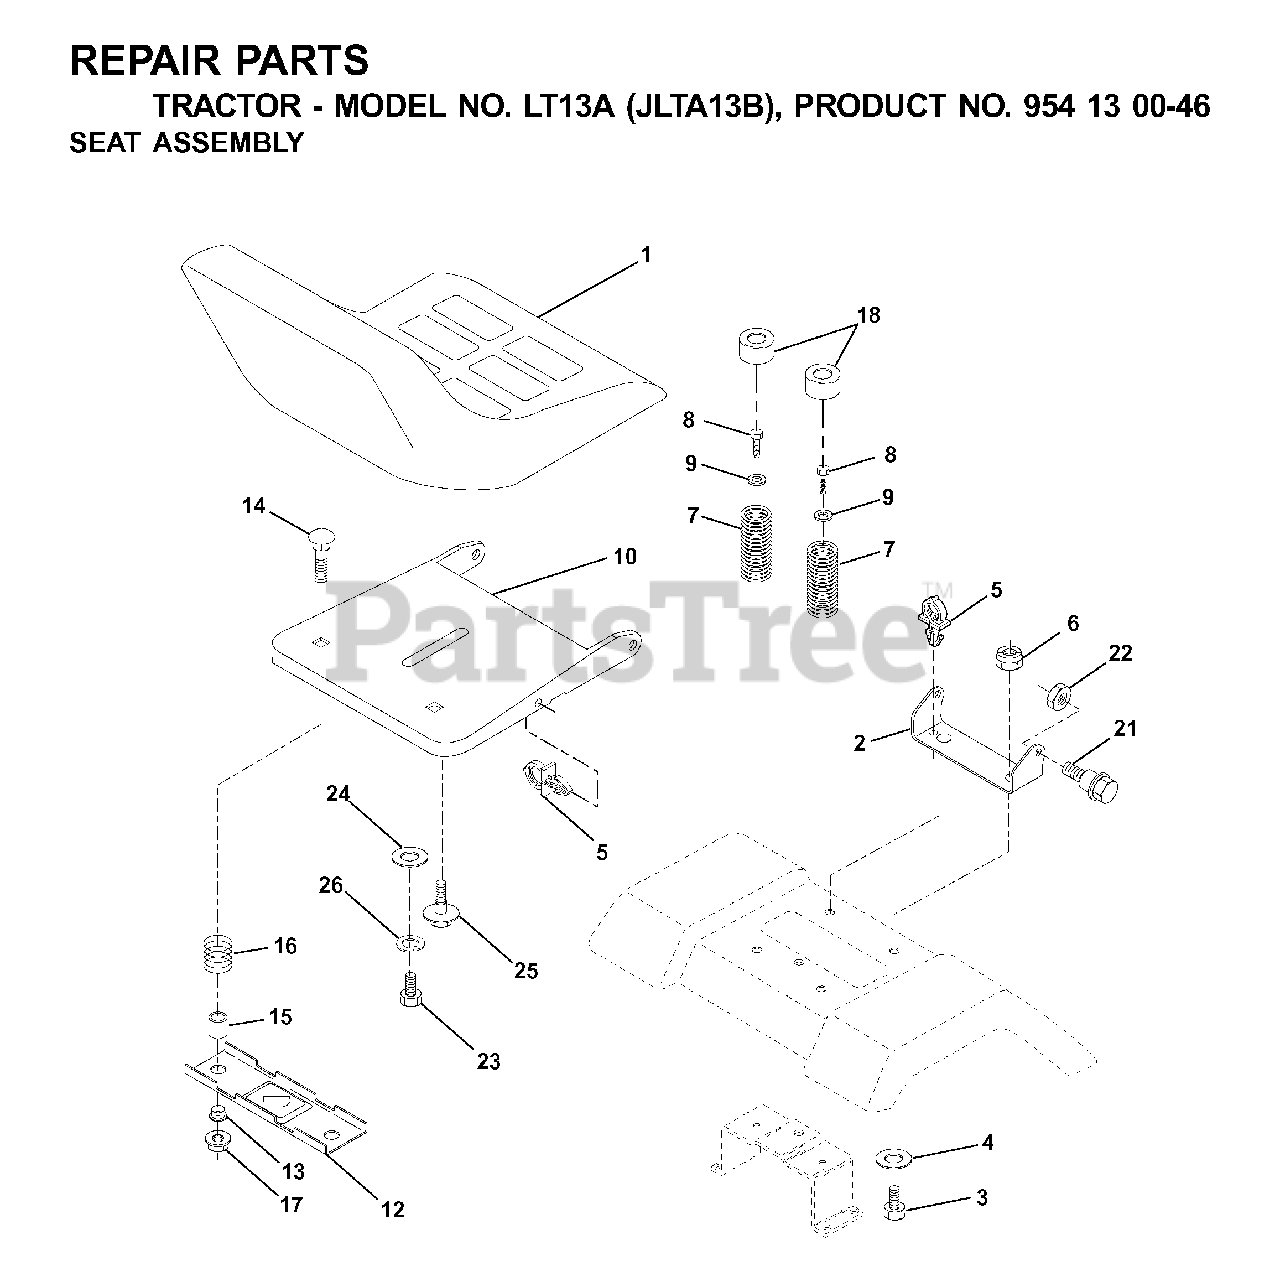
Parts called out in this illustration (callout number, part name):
2	SEAT PIVOT BRKT
4	WASHER PM
5	PUSH CLIP
6	NUT
7	SPRING COMPRESSION
8	SCREW 3/8-16X1
9	WASHER
10	PAN, SEAT
12	BRKT SWITCH
14	BOLT.ROUND.HEAD.SQUARE.NECK
15	SPACER SPLIT 28X.96
17	NUT T
18	CAP SPRING
21	BOLT.SHOULDER.5/16-18
22	NUT.71038.31-18.HEX.NYLOCK
23	BOLT.HEX.BLACK
25	BOLT,SHOULD
26	LOCKWASHER
